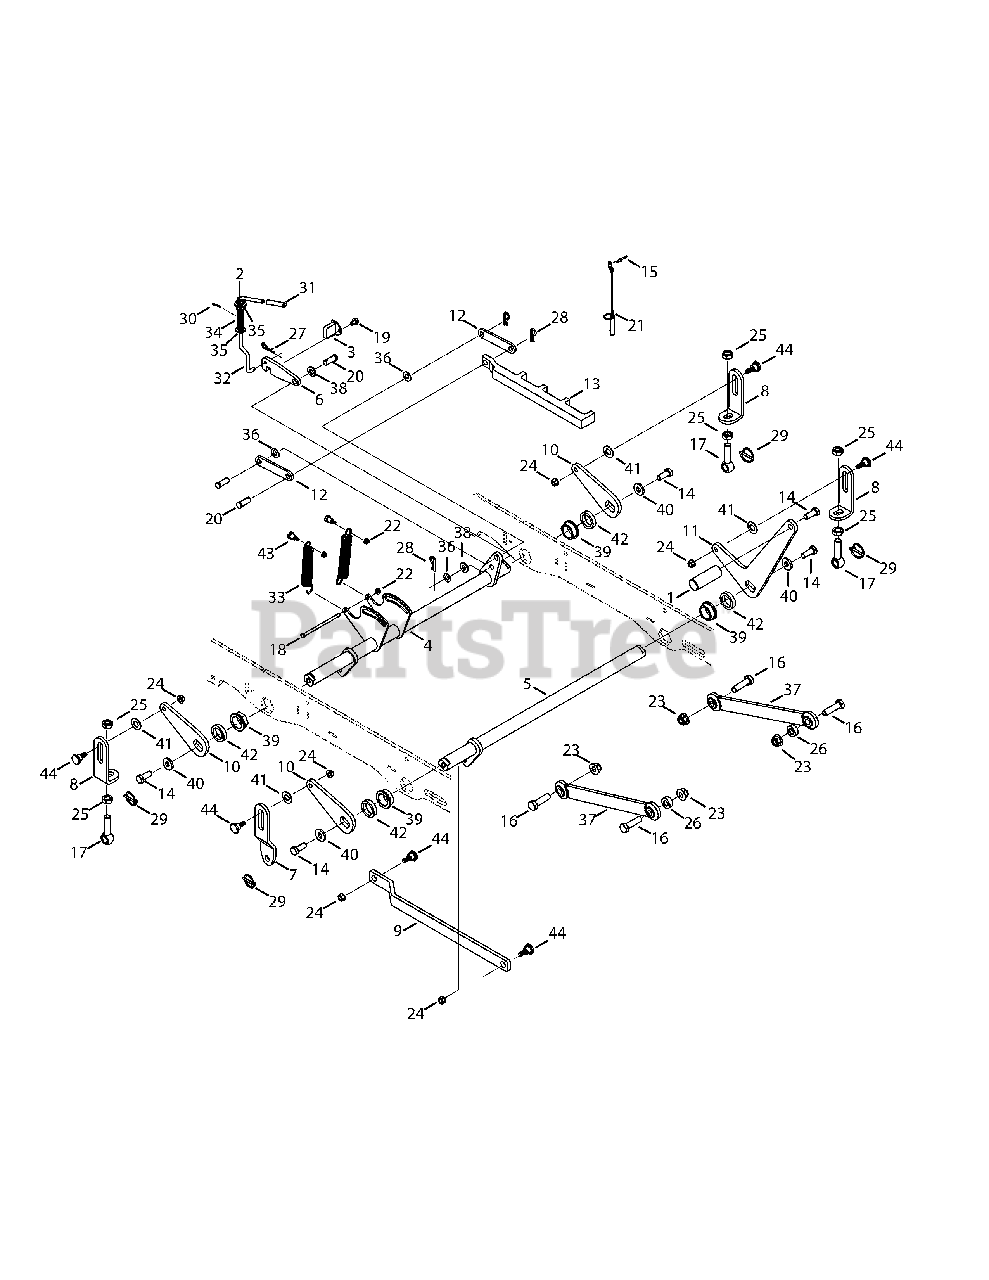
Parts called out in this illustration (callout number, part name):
1	Deck Lift Foot Pedal
2	Bearing, .385 ID
3	Lift Lock Mount
4	Deck Lift Shaft
5	Deck Lift Shaft, Front
6	Latch Lock Bracket
7	Lift Link Arm
8	Deck Adjustment Lift Link Arm
9	Deck Lift Bar, Front
10	Deck Lift Bellcrank
11	Deck Lift Foot Pedal
12	Deck Index Link Arm
13	Lift Index Slider Arm
14	Hex Cap Screw, 1/2-13 x 1.25
15	Rivet, 3/16 x .325
16	Hex Cap Screw, 5/8-11 x 2.25
17	Eye Bolt, 5/8-18 x 2.63
18	Hex Cap Screw, 1/4-20 x 5.00
19	Screw, 5/16-18 x .500
20	Clevis Pin, .500 x 1.25
21	Clevis Pin, .438 x 1.5
22	Nut, 1/4-20, Flangelock
23	Nut, 5/8-11, Flangelock
24	Nut, 3/8-16, Flange Centerlock
25	Jam Nut, 5/8-11
26	Spacer, .635 x 1.25 x .445
27	Click Pin, .092 x 1.64
28	Internal Cotter Pin
29	Lynch Pin, .1875
30	Cotter Pin, 3/32 x .750
31	Lift Handle Grip
32	Lift Lock Rod
33	Extension Spring, .969 OD x 6.180
34	Compression Spring, .656 OD x 2.445
35	Bevel Washer, .340 x .872 x .060
36	Washer, .510 x 1.00 x .125
37	Deck Rod Assembly
38	Washer, .510 x 1.00 x .125
39	Hex Flange Bearing
40	Flat Washer, .531 x 2.125 x .250
41	Washer, .640 x 1.25 x .050
42	Spacer, 1.27 x 1.75 x .375
43	Shoulder Screw, .437 x .50, 1/4-20
44	Shoulder Screw, .625 x .442, 3/8-16
